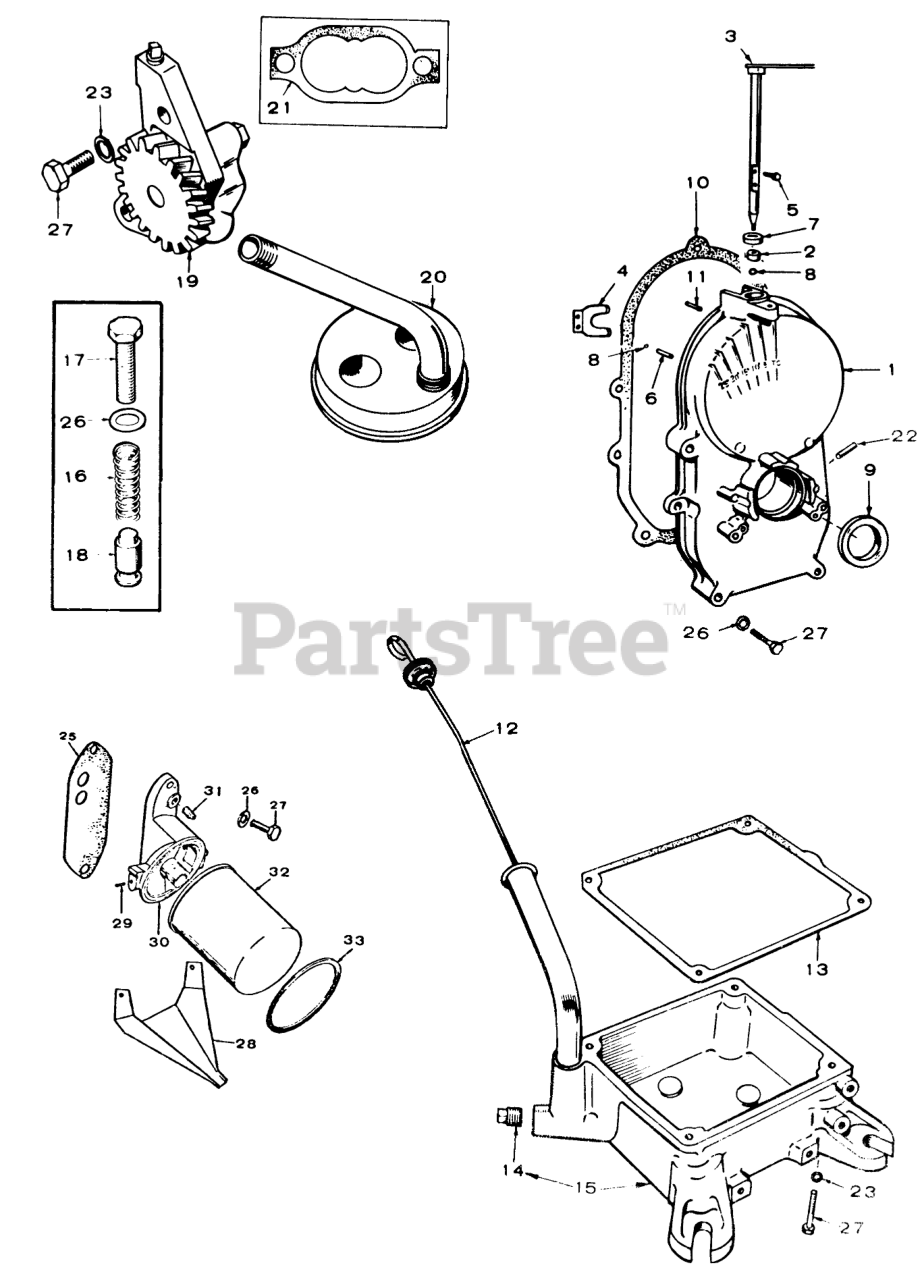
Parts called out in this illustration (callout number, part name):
1	COVER ASSEMBLY, GEAR (Includes Parts Marked )
2	Governor Shaft Bearing
3	Shaft and Arm Assy-Governor
4	Yoke-Governor Shaft
5	Yoke Retaining Screw
6	Pin,Governor-Cup Stop
7	Oil Seal-Governor Shaft
8	Ball Bearing-Governor Shaft
9	Seal-Gear Cover
10	Gasket-Gear Cover Mounting
11	Pin, Gear Cover (5/16 x 1/8)
12	OIL FILL-CAP&INDICTR
13	Oil Base Mounting Gasket
14	Oil Drain Plug
15	Oil Base
16	Spring-Oil By-Pass Valve
17	Screw-Oil By-Pass 3/8-24 X 1
18	Oil By-Pass Valve
19	Oil Pump-Complete
20	Intake, Oil Pump (Includes Cup, Screen, and Pipe)
21	Oil Pump Gasket Kit
22	Fuel Pump Vacuum Tube
23	WASHER, LOCK
23	Oil Base Mounting (3/8")
23	Oil Pump Mounting (1/4")
25	Gasket-Oil Filter Pad Cover
26	WASHER, FLAT
26	Copper Washer-3/8 Oil Filter
26	Copper Washer-3/8 Oil Pressure
26	Copper Washer 5/16 Gear Cover
27	SCREW, HEX CAP
27	Hex Bolt-Oil Filter Adapter
27	Hex Bolt-Oil Base To Block
27	Hex Bolt-Gear Cover 1 3/4 Long
27	Hex Bolt-Gear Cover 2 1/4 Long
27	Hex Bolt-Oil Pump 1/4-20 X 1
28	Dain, Oil Filter
29	Hex HD Screw With Et Washer
30	Oil Filter Adapter
31	Square HD Plug
32	Oil Filter
33	Oil Filter Air Seal
